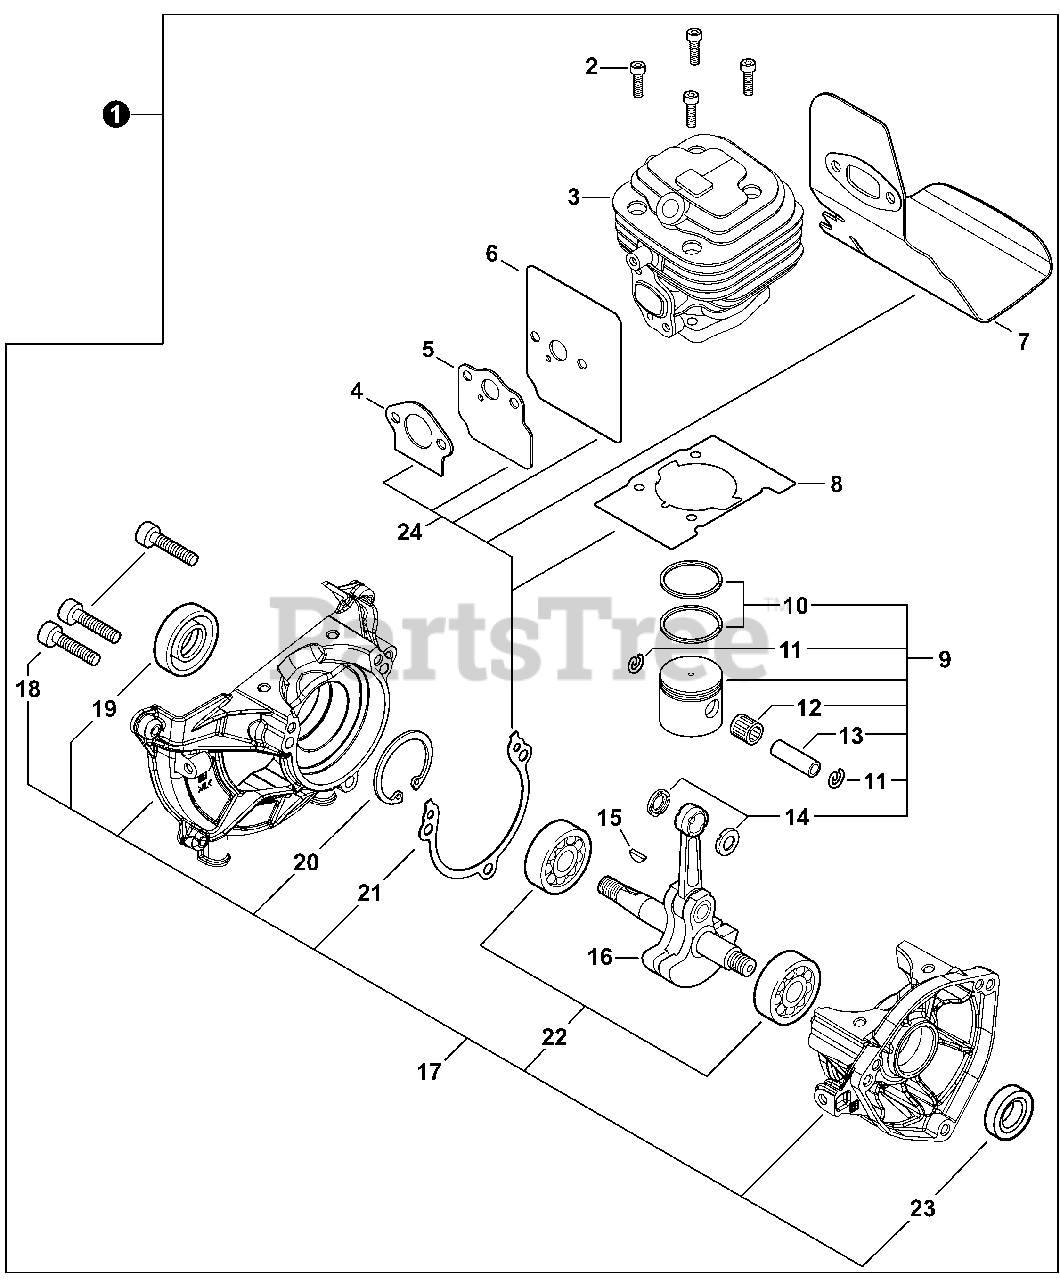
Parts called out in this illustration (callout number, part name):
1	SHORT BLOCK
2	BOLT, TORX 5×20
3	CYLINDER
4	GASKET, INTAKE
5	GASKET, BOOT
6	GASKET, INSULATOR PLATE
7	HEAT SHIELD, EXHAUST
8	GASKET, CYLINDER
9	PISTON KIT
10	RING, PISTON
11	RING, SNAP
12	BEARING, NEEDLE 9
13	PIN, PISTON
14	WASHER, THRUST
15	KEY, WOODRUFF
16	CRANKSHAFT ASSY
17	CRANKCASE KIT
18	BOLT, TORX 5×25
19	SEAL, OIL 12
20	RING, SNAP Ø32
21	GASKET, CRANKCASE
22	BEARING, BALL - 6201 C3
23	SEAL, OIL 12
24	GASKET KIT
